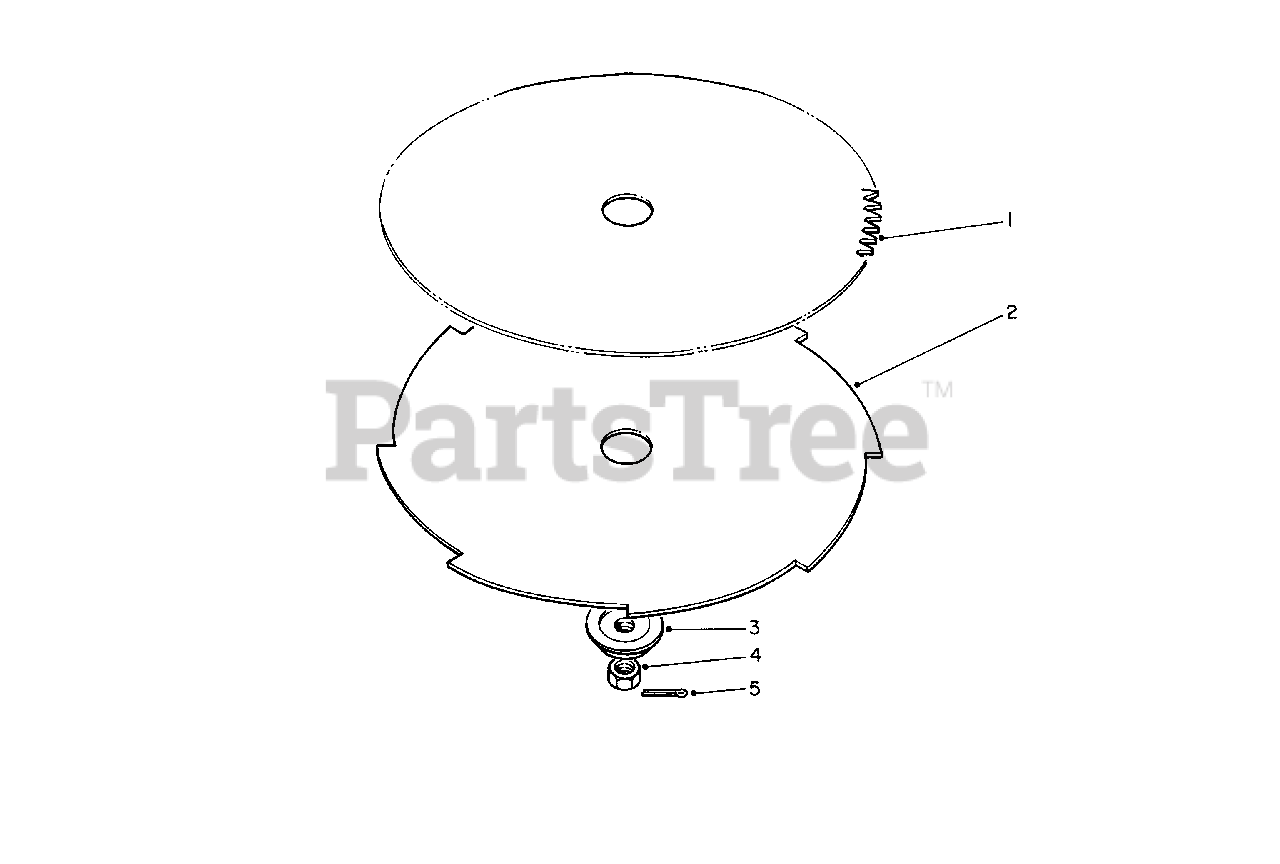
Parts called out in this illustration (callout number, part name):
1	8" Dia. Blade (80 Tooth)
2	8" Dia. Blade (8 Tooth)
3	Adapter-Blade
4	Nut L.H.
5	Pin Cotter
